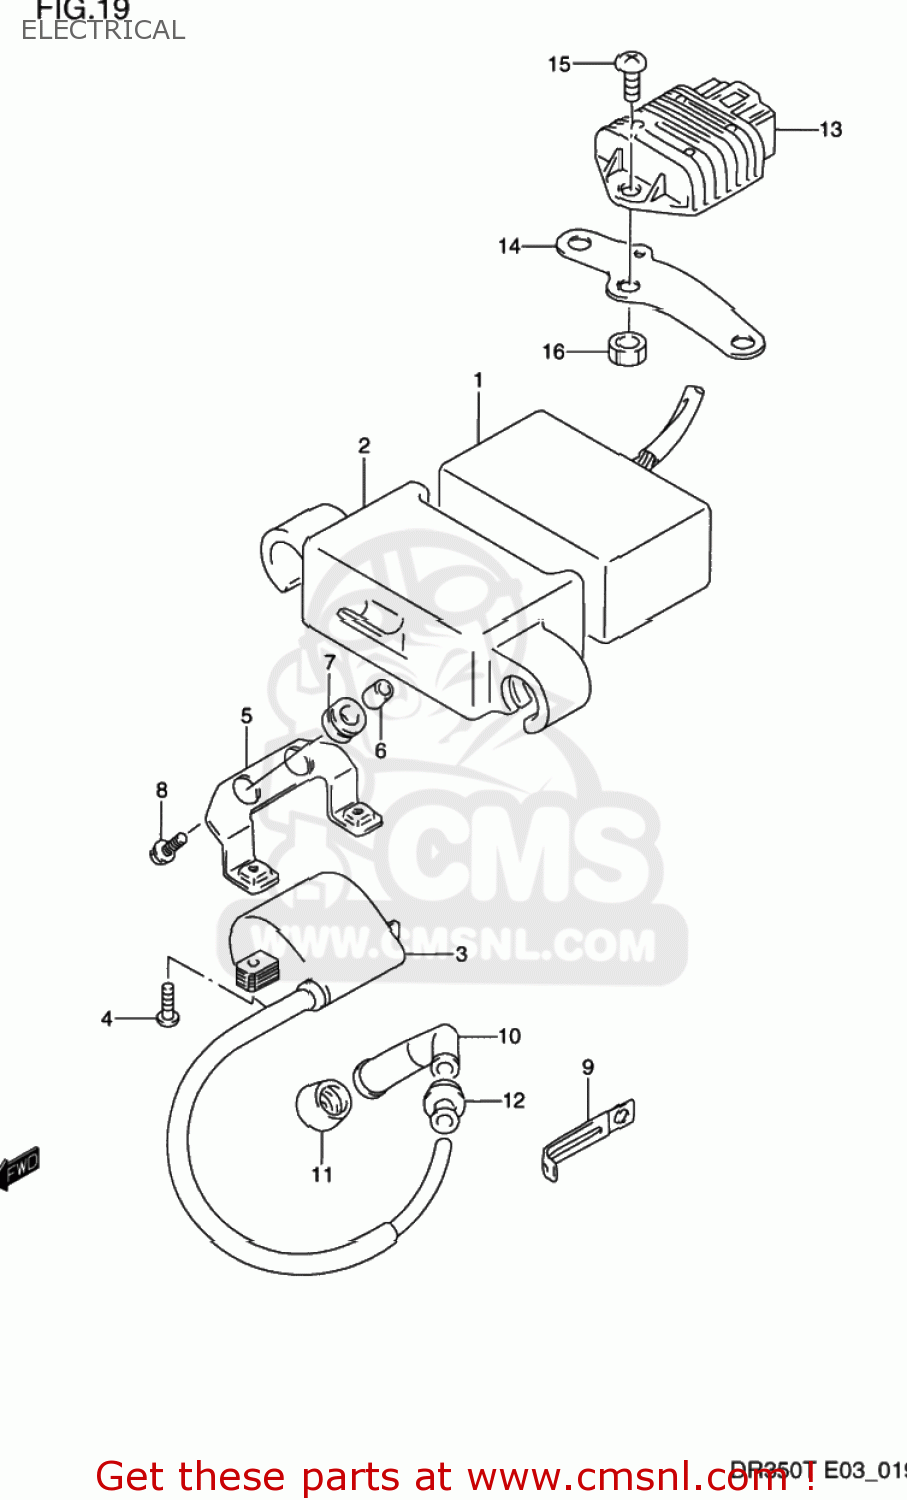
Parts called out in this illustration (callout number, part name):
1	CDI UNIT
2	CUSHION,CDI UNIT
3	COIL ASSY,IGNITION
4	SCREW
5	BRACKET,IGNITION COIL
6	SPACER (6.3X9.1X6.7)
7	CUSHION
8	BOLT
9	CLAMP
10	CAP,SPARK PLUG
11	SEAL,SPARK PLUG
12	SEAL,HIGH TENSION CORD
13	REGULATOR ASSY
14	BRACKET,REGULATOR
15	SCREW
16	NUT
